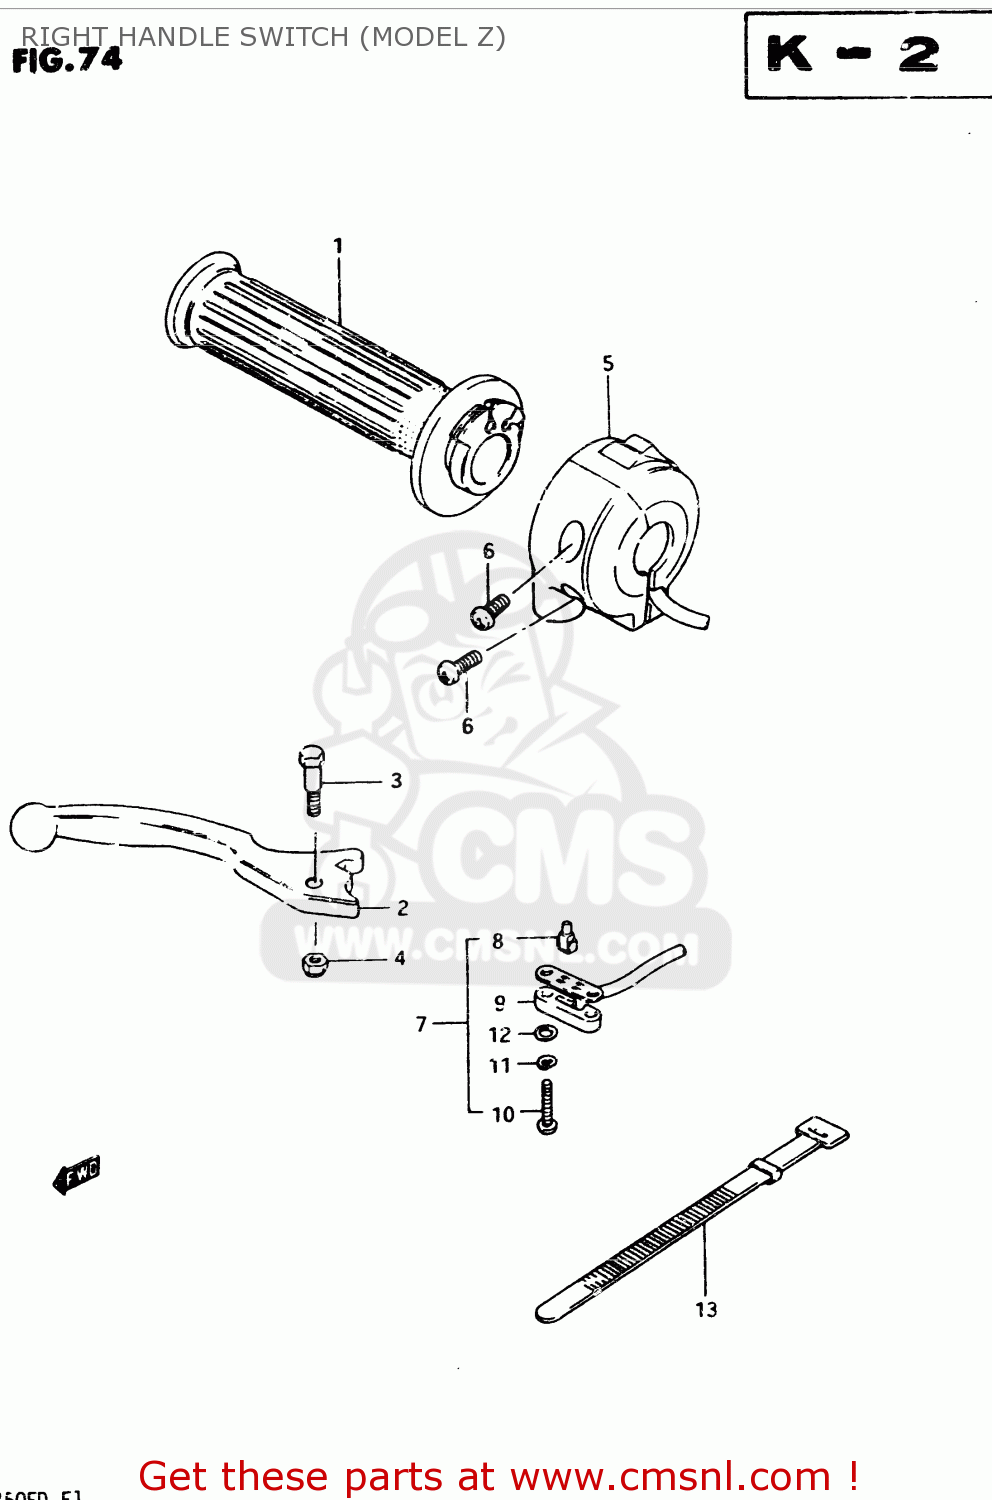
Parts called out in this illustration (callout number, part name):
1	GRIP,THROTTLE
2	LEVER,BRAKE
3	BOLT
4	NUT 6MM
5	SWITCH ASSEMBLY,HANDLE,RIGHT
6	SCREW
7	SWITCH ASSEMBLY
8	CONTACT,SWITCH
9	COVER,FR BK TERMINAL BASE
10	SCREW
11	LOCK WASHER
12	WASHER
13	CLAMP(L:120)
